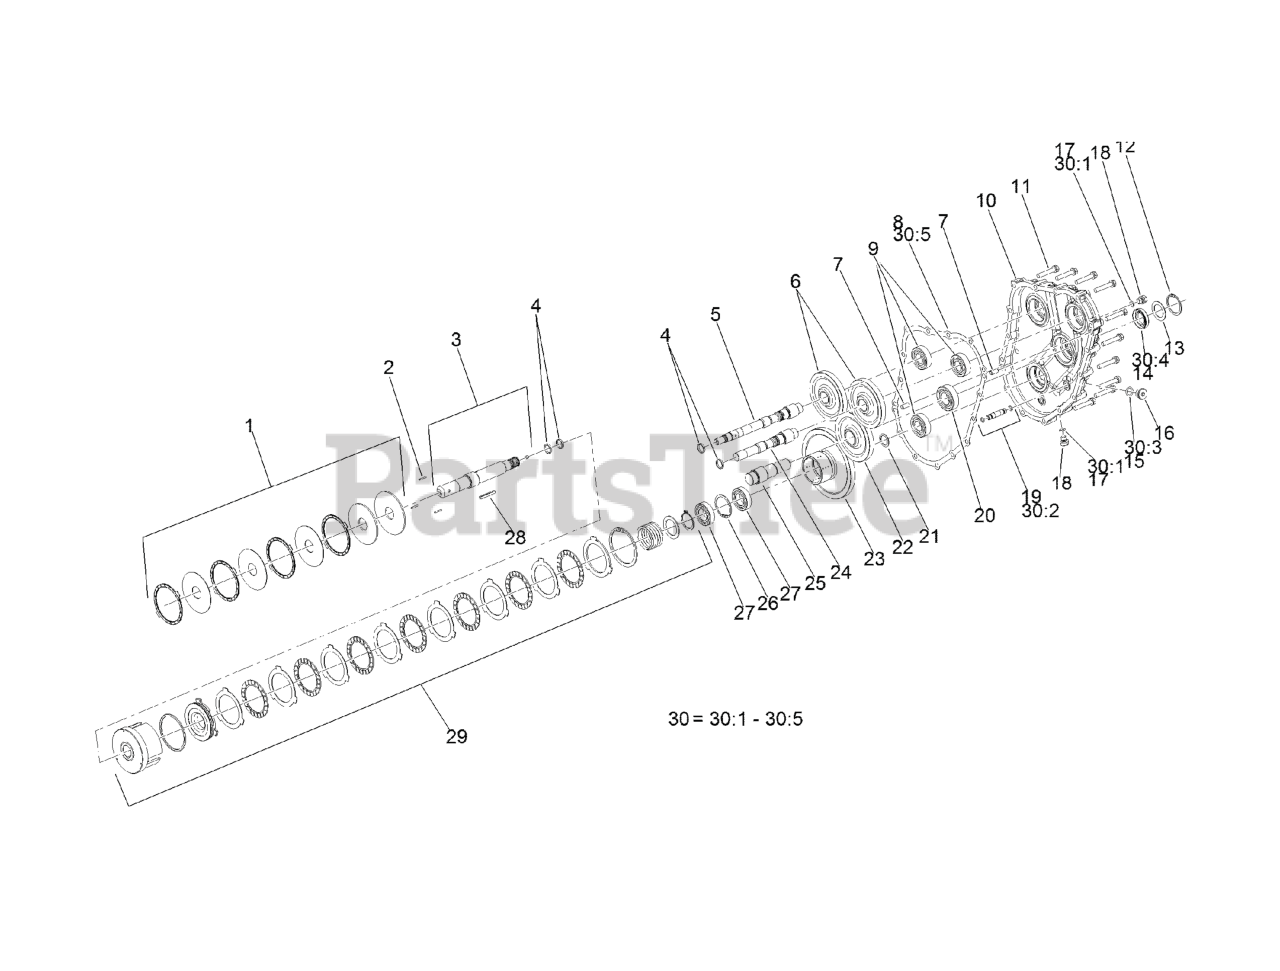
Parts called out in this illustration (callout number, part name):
1	PTO BRAKE ASM
2	ROD-PUSH
3	PTO SHAFT ASM
4	RING-SEAL
5	SHAFT-PUMP
6	GEAR-PUMP
7	PIN-PARALLEL
8	GASKET-HOUSING, GEAR
9	BEARING
10	HOUSING-CASE, GEAR
12	RING-SNAP
15	Packing
16	PLUG-NPTF
17	O RING-PLUG
20	BEARING
22	GEAR-INPUT
23	GEAR-PTO
24	SHAFT-PUMP
25	SHAFT-INPUT
26	RING-SNAP
27	BEARING
29	CLUTCH CYLINDER ASM
30	GEAR HOUSING SEAL KIT
30:1	O RING-PLUG
30:2	O-Ring
30:3	Packing
30:5	GASKET-HOUSING, GEAR
